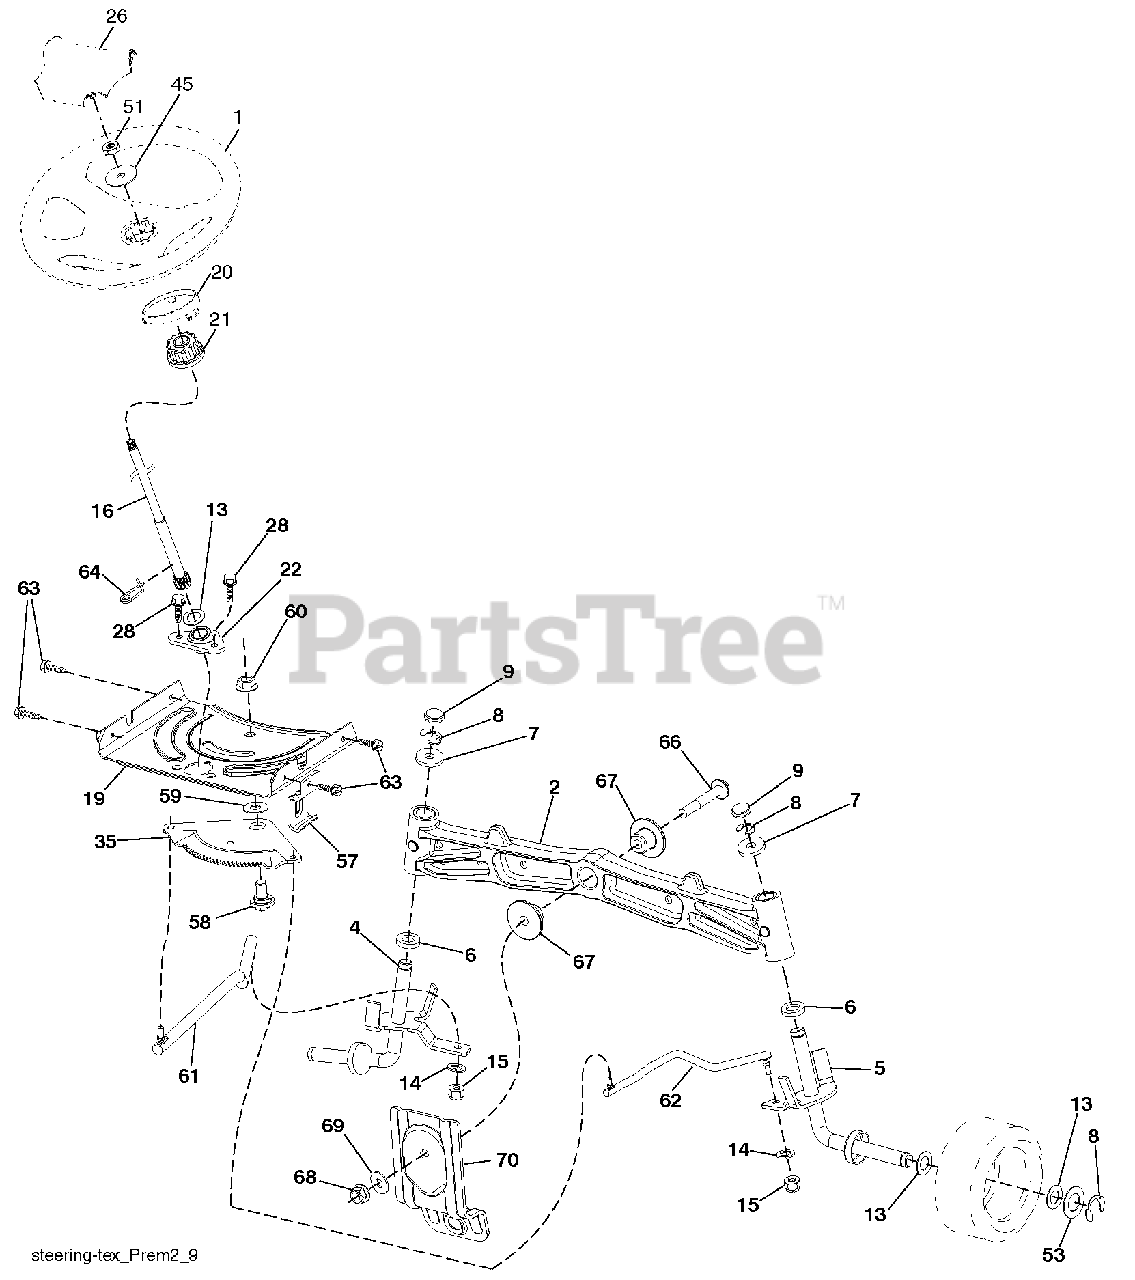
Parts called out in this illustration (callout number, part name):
1	Wheel, Steering
2	Axle Asm., Front
4	Spindle Asm., LH
5	Spindle Asm., RH
6	Bearing, Race Thrust Harden
7	Washer 25/32 x 1-5/8 x 16 Ga.
8	Ring, Clip #T5304-75
9	Cap, Spindle
13	Washer 25/32 x 1-1/4 x 16 Ga.
14	Washer, Lock Hvy Hlcl Spr 3/8
15	Nut, Crown Lock 3/8-24 unf
16	Shaft Steering
19	Plate Steering
20	Boot, Steering
21	Adapter, Wheel Steering
22	Steering Support Lower
26	Insert, Wheel Steering
28	Screw 3/8-16 x 3/4
35	Gear, Sector Plate
45	Washer 9/16 ID x 2-3/8 x 12 Ga.
51	Nut Hex Jam Toplock 1/2-20 unf
53	Washer Hardened .793 x 1.637 x .060
57	Bracket Upstop
58	Bolt Shoulder Sector Pivot CFM
59	Washer Thrust Sector Steering
60	Nut Flange Lock 5/8-11
61	Draglink, LH
62	Draglink, RH
63	Screw 5/16-18 x 3/4
64	Retainer Clip Spring Steering
66	Bolt Hex Fghd 7/16-14 x 3 Serr
67	Bushing PM Front Axle
68	Nut Lock Flange 7/16-14 Gr. 5
69	Washer 1.5 x .505 x .118
70	Bracket Deck Susp. Front
